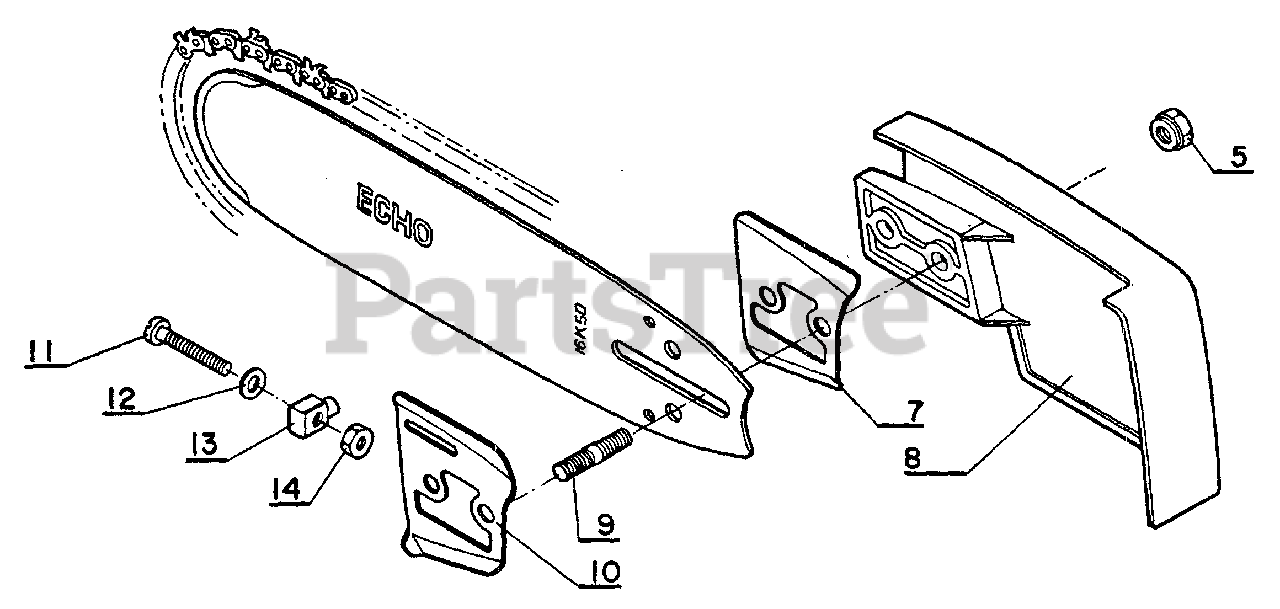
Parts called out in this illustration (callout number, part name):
5	NUT - FLANGE
7	PLATE, GUIDE - OUTER
8	GUARD, SPROCKET
9	STUD, GUIDE BAR
10	PLATE, GUIDE - INNER
11	SCREW, TENSIONER
12	WASHER - 5
13	TENSIONER, CHAIN
14	LOCKNUT - 5
